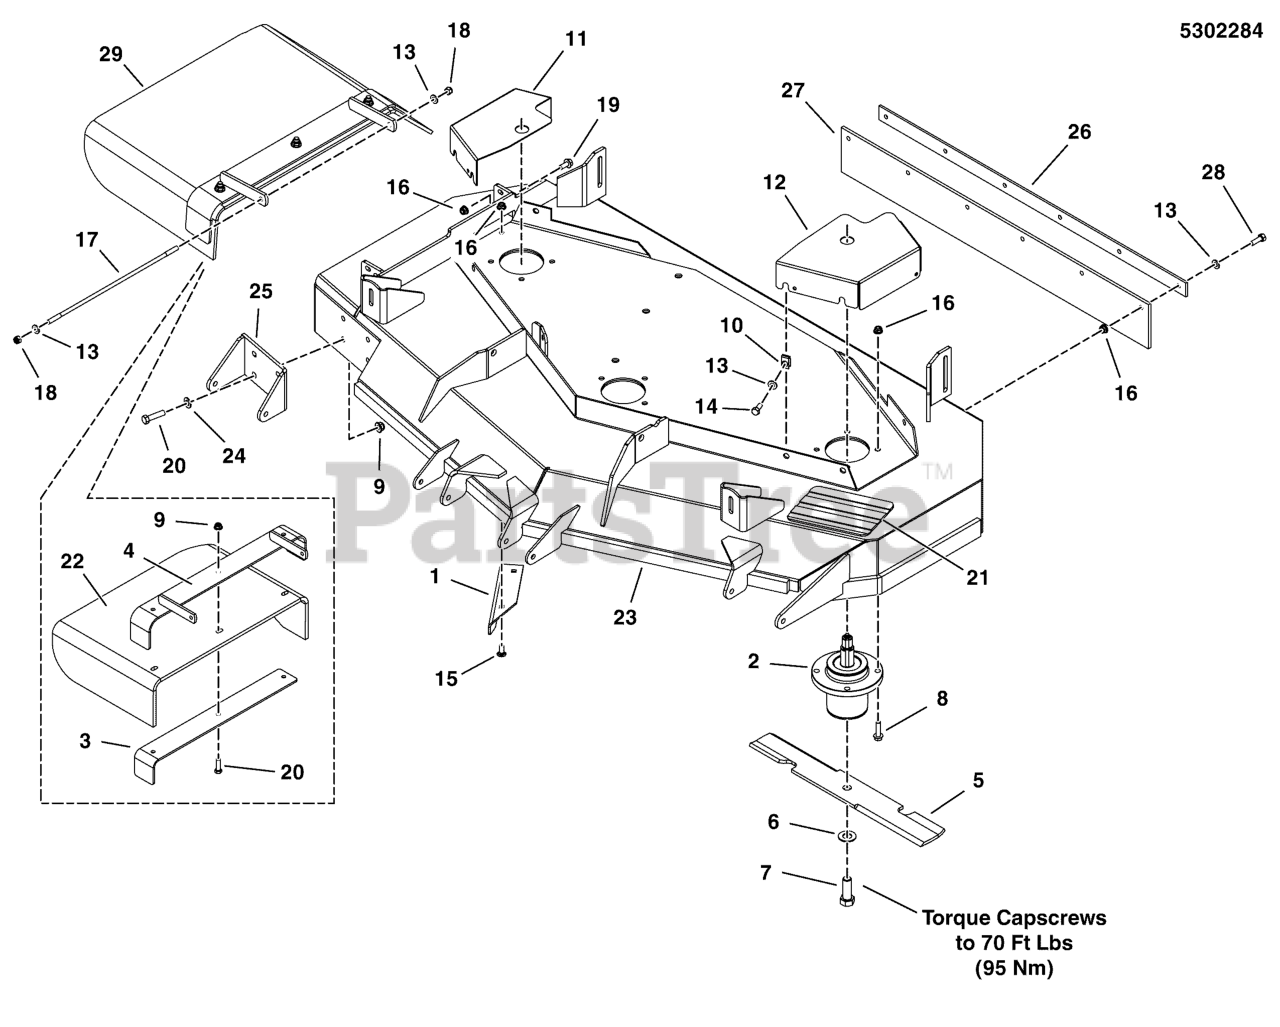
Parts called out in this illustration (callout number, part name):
1	PLATE, DEFLECTOR - BLK
2	ASSM, SPINDLE, LOW PROFILE
3	SUPPORT, DISCHARGE CHUTE - BLK
4	WELD, FRAME, CHUTE, 61 - RED
5	BLADE, 18 X .25 X 2.5, 1 X 3.5 (SET OF 3)
6	WASHER, 5/8 GRADE 8, YZ
7	BOLT, 5/8-11 X 1-3/4 GD8
8	BOLT, 5/16-18 X 1 1/4 FLANGE
9	NUT, 3/8-16 HEX NYLOCK FLANGE
10	BODY CLIP, 5/16-18-7GA MATERIAL
11	GUARD, 52 DECK, IS2000, RH - RED
12	GUARD, 52" DECK, IS2000 - LH - RED
13	WASHER, 5/16" SAE
14	BOLT, 5/16-18 X 3/4 GD5
15	BOLT, 5/16-18 X 3/4, CARRIAGE
16	NUT, 5/16-18 HEX NYLOCK FLANGE
17	ROD MOUNT, CHUTE 61"
18	NUT, 5/16-24 HEX NYLON LOCK
19	BOLT, 5/16-18 X 3/4 GD5
20	BOLT, 3/8-16 X 1-1/2" GD5 CZ
21	SAFETY WALK, 4.00 X 7.50
22	CHUTE, DISCHARGE, RUBBER, 61/72
24	WASHER, 3/8 SAE
25	PLATE, BRACKET, ANTI SCALP - RED
26	PLATE, SUPPORT - BLK
27	FLAP, STRIPER, 52 DECK
28	BOLT, 5/16-18 X 1 GD5 YZ
29	KIT, DISCHARGE CHUTE
